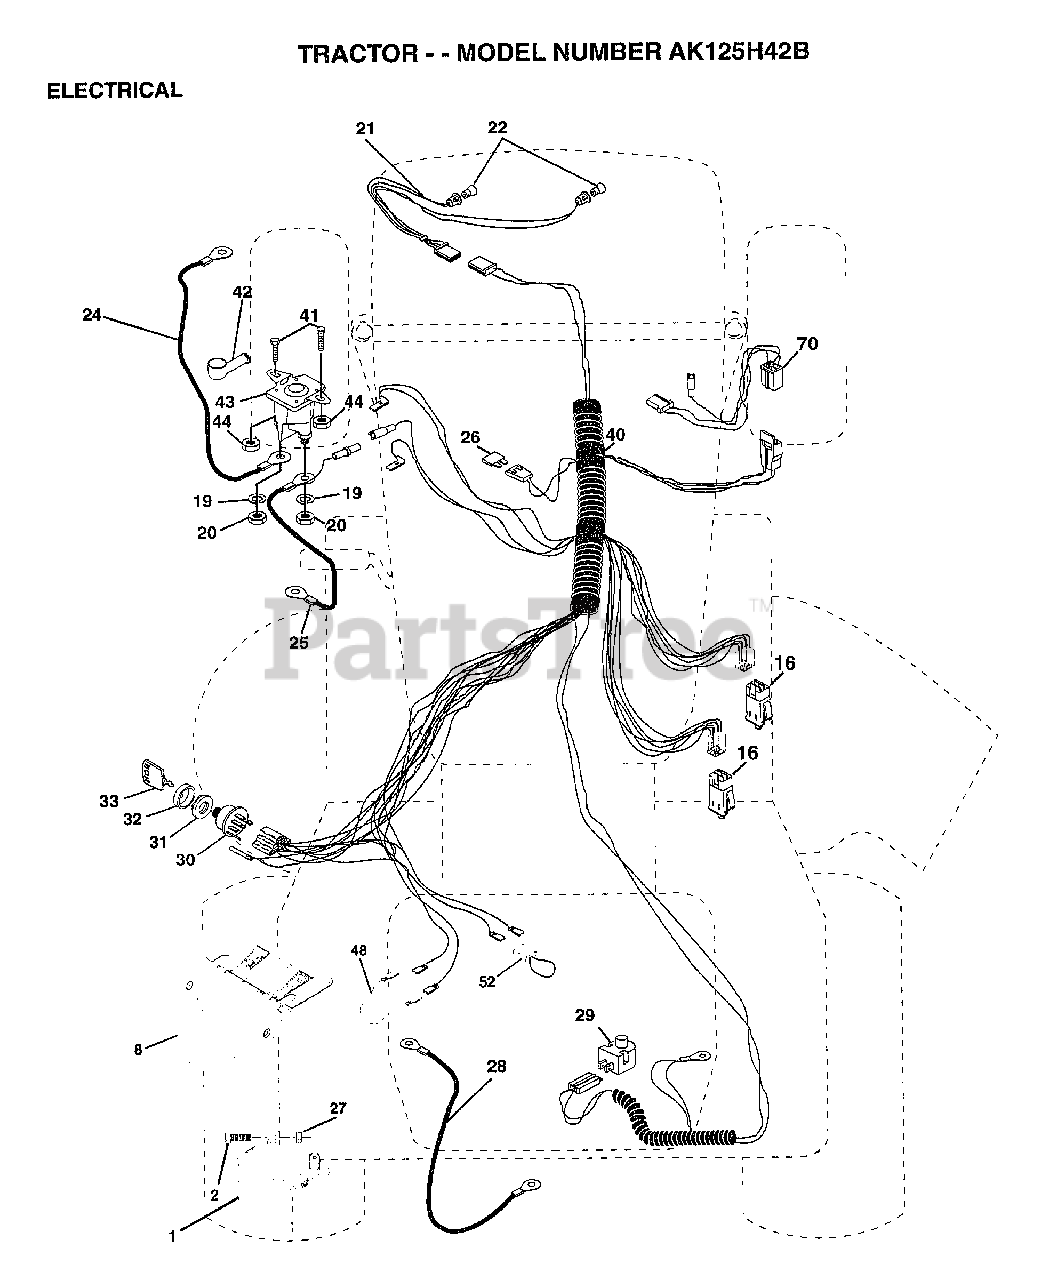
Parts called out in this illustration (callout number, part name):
2	BOLT LT
8	"CASE,BATTERY.MECH"
16	SWITCH INTERLOCK
20	NUT
21	HARNESS.ASM.LIGHT W/4152J
22	HEADLAMP BULB
24	"CABLE T, BATTERY"
25	CABLE.BTRY.6GA.RD
26	FUSE.15 AMP
27	NUT
28	CABLE T
29	SWITCH SEAT
30	SWITCH IGN 4POS
31	NUT IGNITION
32	COVER KEY SWITCH
33	KEY
40	HARNESS.IGNITION
41	BOLT HXHD FIN
44	NUT HXKEP 1/4X20
48	ADAPTER AMMETER
52	PROTECTION LOOP
70	HARNESS.ENGINE
